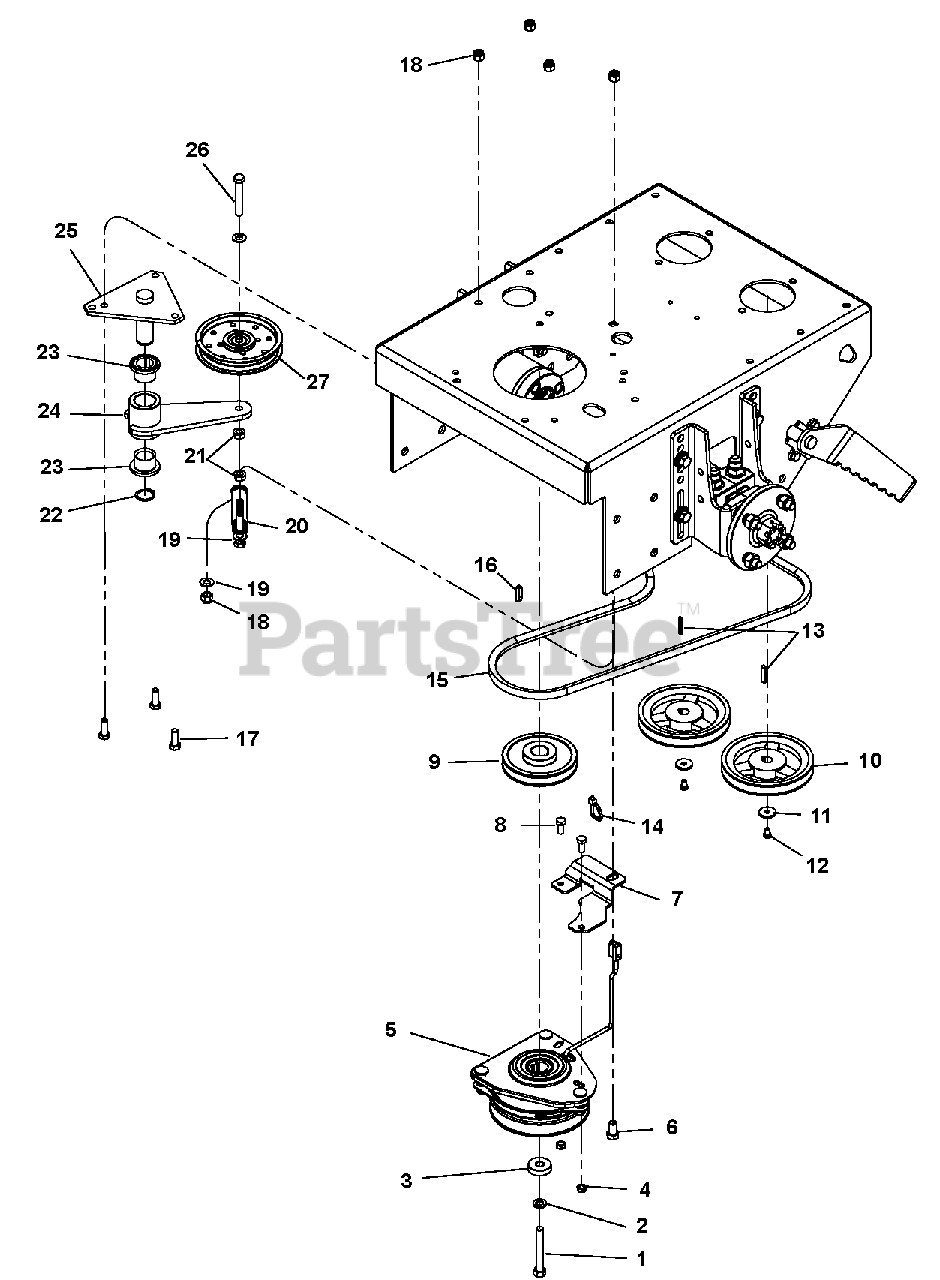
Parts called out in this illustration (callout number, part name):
1	Bolt, .44-20 x 3.00 Hex Grade 5
2	Washer, .438 Medium Spring Lock
3	Spacer, .468 x 1.38 x .375
4	Locknut, .3125-18 Nyloc
5	Clutch Assembly, OGURA
6	Bolt, .4400-14 x .750 Hex Grade 5
7	Plate, Clutch Dog
8	Bolt, .31-18 x .750 Hex Grade 5
9	Pulley, V-Belt 4.45 x 1.00 with Key
10	Assembly, Plump Pulley w/Set Screw
11	Washer, .250 Wide Heavy Flat
12	Bolt, M6 x 1.00 x 10 Hex 8.8
13	Key, M5 x M5 x M30 RD
14	Cable Tie, .15 x 8.50
15	Belt, HA 55.1 Elbow AMD OHR
16	Key, .250 x .250 x .995 TPR
17	Bolt, .38-16 x 1.00 Hex Grade 5
18	Locknut, .38-16 Nyloc
19	Washer, .406 x .813 x .065 Flat
20	Spring, External .900 x .135 x 4.50
21	Locknut, .38-16 WHIZ
22	Snap Ring, 1.00 x .042 External
23	Bearing, Flange 1.00 x 1.25 x 1.00
24	Weldment, Idler Arm
25	Weldment, Idler Pivot Mount
26	Bolt, .38-16 x 2.50 Hex Grade 5
27	Pulley, Flat 4.50 x .375 W/BRG
